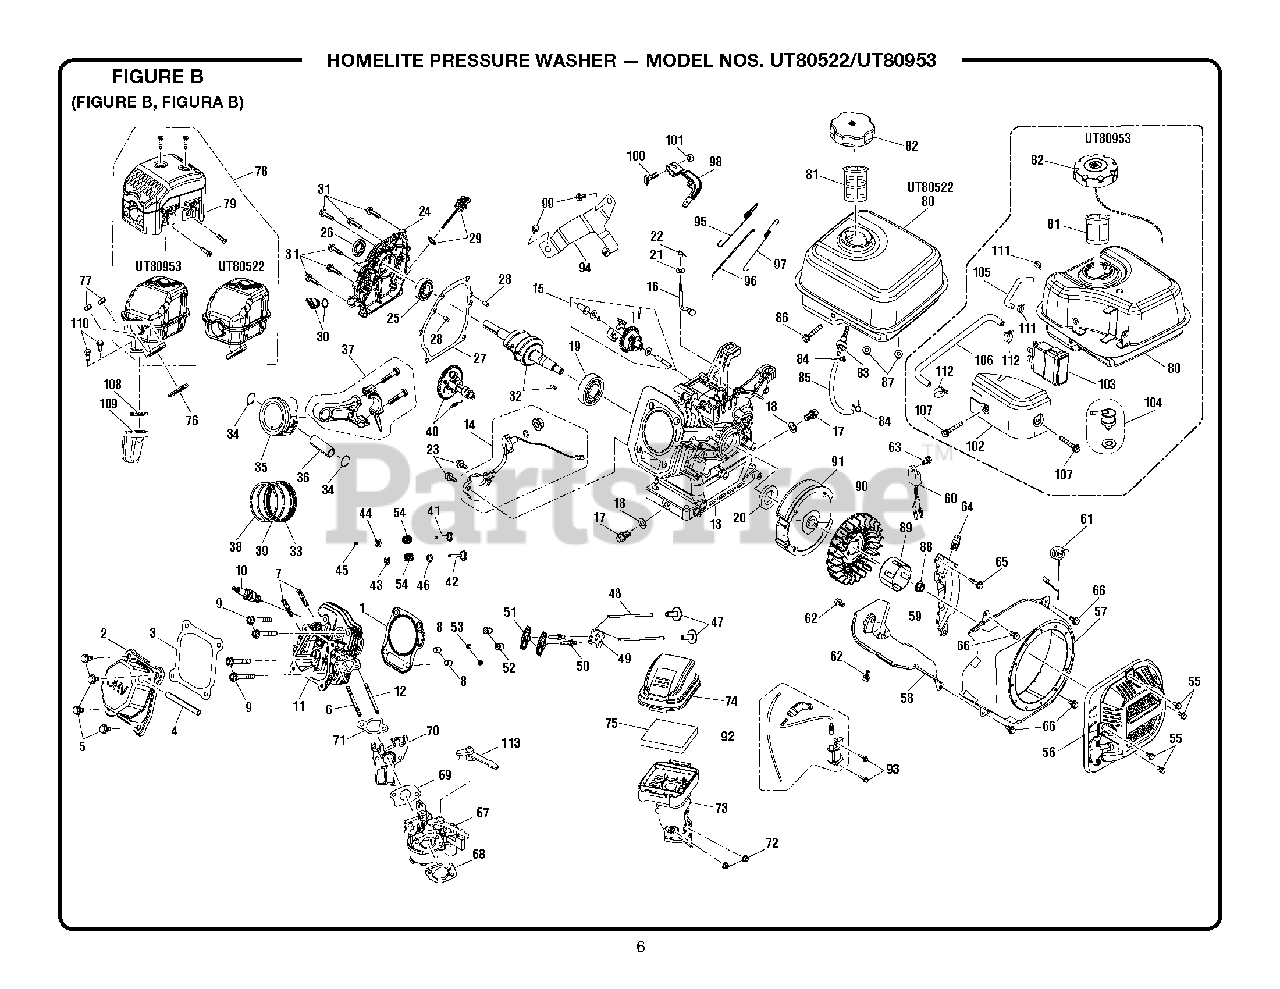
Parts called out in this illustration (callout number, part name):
1	Cylinder Head Gasket
2	Cylinder Head Cover Assembly
3	Cylinder Head Cover Gasket
4	Breather Tube
9	Cylinder Head Bolt
10	Spark Plug (Champion RC12YC)
11	Cylinder Head Assembly
13	Crankcase Assembly
14	Engine Oil Sensor
15	Governor Gear Assembly
16	Governor Arm
17	Drain Plug Bolt
21	Governor Gear Washer
24	Crankcase Cover Assembly
27	Crankcase Gasket
29	Oil Dipstick Assembly
30	Engine Oil Plug Assembly
32	Crankshaft Assembly
33	Oil Ring Set
34	Piston Pin Clip
35	Piston Assembly
37	Connecting Rod
39	Second Ring
40	Camshaft Assembly
41	Exhaust Valve
42	Intake Valve
43	Valve Spring Seat
44	Exhaust Valve Retainer
45	Valve Rotator
47	Valve Tappet
48	Valve Lifter
49	Lifter Stopper Plate Assembly
50	Valve Adjusting Bolt
51	Valve Rocker
52	Valve Adjusting Nut
53	Valve Lock Nut
54	Valve Spring
55	Bolt
56	Recoil Starter Assembly
58	Cylinder Body Shroud
59	Lower Shield
60	Oil Protector
61	Stop Engine Switch Assembly
67	Carburetor Assembly
68	Air Cleaner Gasket
69	Carburetor Gasket
70	Carburetor Insulator Plate
71	Carburetor Insulator Gasket
73	Air Cleaner
74	Air Cleaner Case Cover
75	Air Cleaner Element
76	Exhaust Outlet Gasket
78	Muffler Assembly
79	Muffler Outer Cover
80	Fuel Tank
81	Fuel Strainer
82	Fuel Tank Cap
83	Fuel Tank Outlet Assembly
89	Starter Pulley
91	Flywheel Assembly
92	Ignition Coil
94	Throttle Control Assembly
95	Governor Spring
96	Governor Rod
97	Throttle Valve Return Spring
98	Governor Support Assembly
100	Governor Support Bolt
102	Canister Cover
103	Carbon Canister
104	Rollover Valve
105	Vapor Line
106	Vapor Line
107	Bolt
108	Air Valve Gasket
109	Muffler Air Valve
110	Bolt
111	Clamp
112	Clamp
113	Choke Lever
